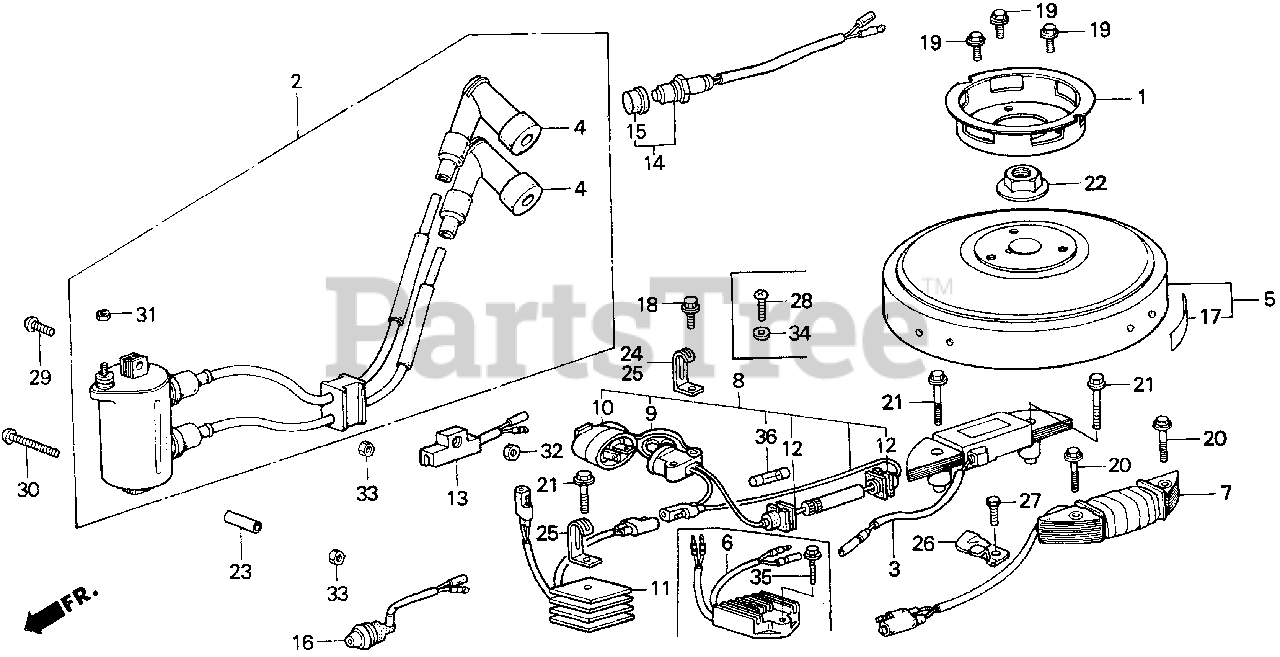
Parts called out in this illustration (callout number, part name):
1	PULLEY, STARTER
2	COIL ASSY., C.D.I. IGNITION
3	COIL ASSY., EXCITER
4	CAP ASSY., NOISE SUPPRESSOR
5	FLYWHEEL *TBLACK* (BLACK)
7	COIL ASSY., CHARGE
19	BOLT, FLANGE (6X12)
20	BOLT, FLANGE (6X28)
21	BOLT, FLANGE (6X35)
22	NUT, SPECIAL (14MM)
23	COLLAR, DISTANCE
24	CLIP, TUBE
25	CLIP, WIRE
26	CLIP, WIRE
27	SCREW, PAN (6X12)
29	SCREW, PAN (6X28)
30	SCREW, PAN (6X50)
31	NUT, HEX. (5MM) (NOT AVAILABLE)
33	NUT, HEX. (6MM)
